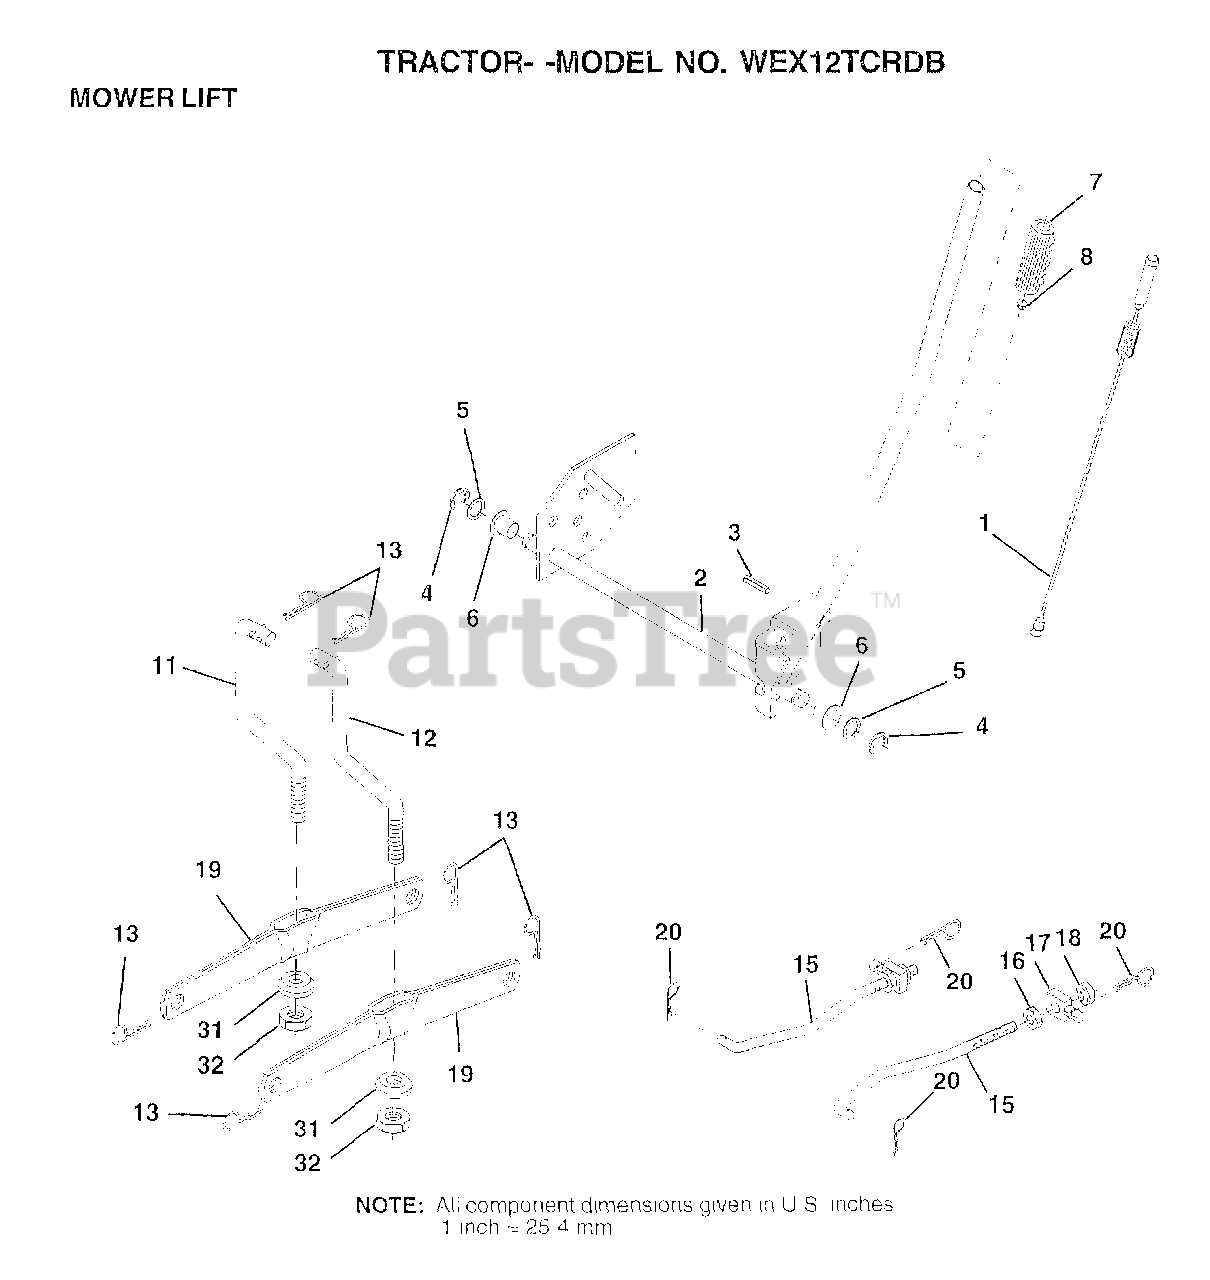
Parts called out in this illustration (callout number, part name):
1	WIRE ASM W.SPRING
2	"SHAFT ASM LIFT,RH"
3	PIN-GROOVE LT
5	WASHER
6	NYLON BEARING
7	GRIP
11	LINK.LIFT.LH.CRD
12	LINK.LIFT.RH.CRD
15	LINK, FRONT
16	NUT
17	TRUNION
18	NUT.LK.W/WSH.1/2.
19	ARM SUSP REAR
20	RETAINER SPRING
31	BEARING PVT LH
32	NUT.CROWNLOCK.3/8
